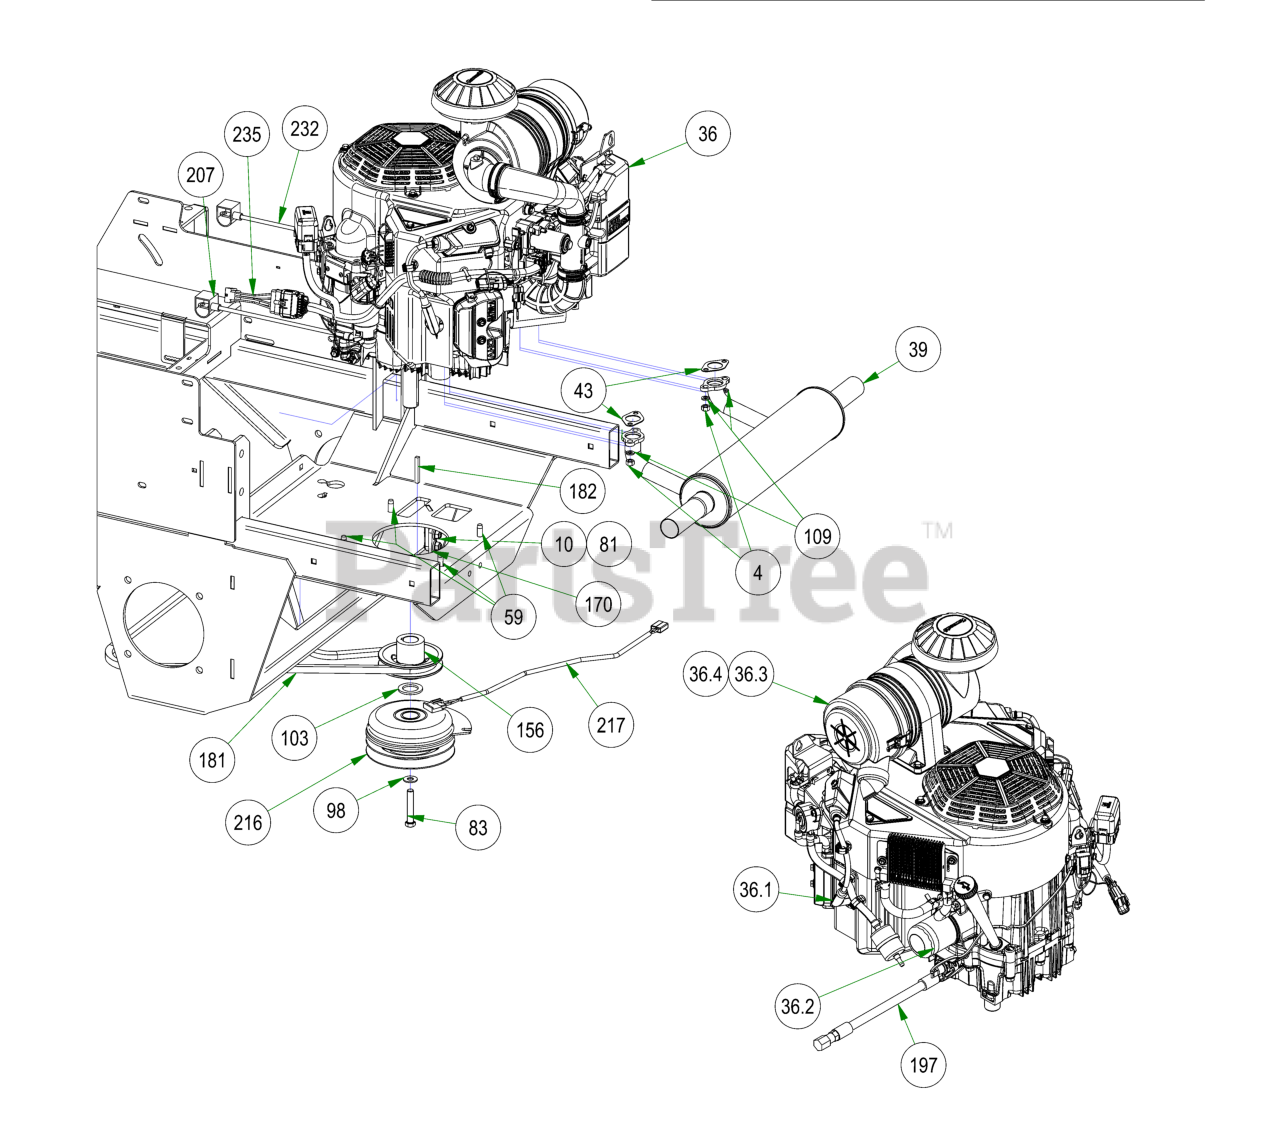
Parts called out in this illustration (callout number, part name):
4	M8-1.25 DIN 934 HEX NUT (CL.8) ZINC
10	3/8-16 NYLON INSERT FLANGE LOCKNUT (GR.F) ZINC
36	Kawasaki FX850V EFI 29.5hp
36.1	Spark Plug - Kawasaki
36.2	Oil Filter
36.3	Canister Air Filter- Outer
36.4	Canister Air Filter- Inner
39	2019 Rebel/Rogue Kawasaki 850 Muffler
43	Exhaust Gasket
59	3/8-16 X 1-1/8HEX WASHER UNSLOT SERRATED
81	3/8-16 X 1 CARRIAGE BOLT (GR.5) ZINC
83	7/16-20 X 2-1/2 HEX Bolt GR 8 W/ Patch
98	3/8 FLAT WASHER USS (1" OD) ZINC
103	1.140 ID X 1.750 OD X .132 THICK FLAT WASHER PLAIN
109	5/16 SPLIT LOCKWASHER ZINC
156	4 3/4 Motor Pulley
170	Rebel Clutch Tab
181	2019 Rebel Pump Belt
182	1/4 X 2 SQ MACHINERY KEY 1018 STL PLAIN
197	Kawasaki Oil Drain
207	14" Red Battery Cable-Base Outlaw
216	Clutch Assembly
217	Clutch Pigtail
218	2022 Rebel Frame
232	Starter Cable
235	2019 Harness Adaptor-Gen2 FX-ALL
